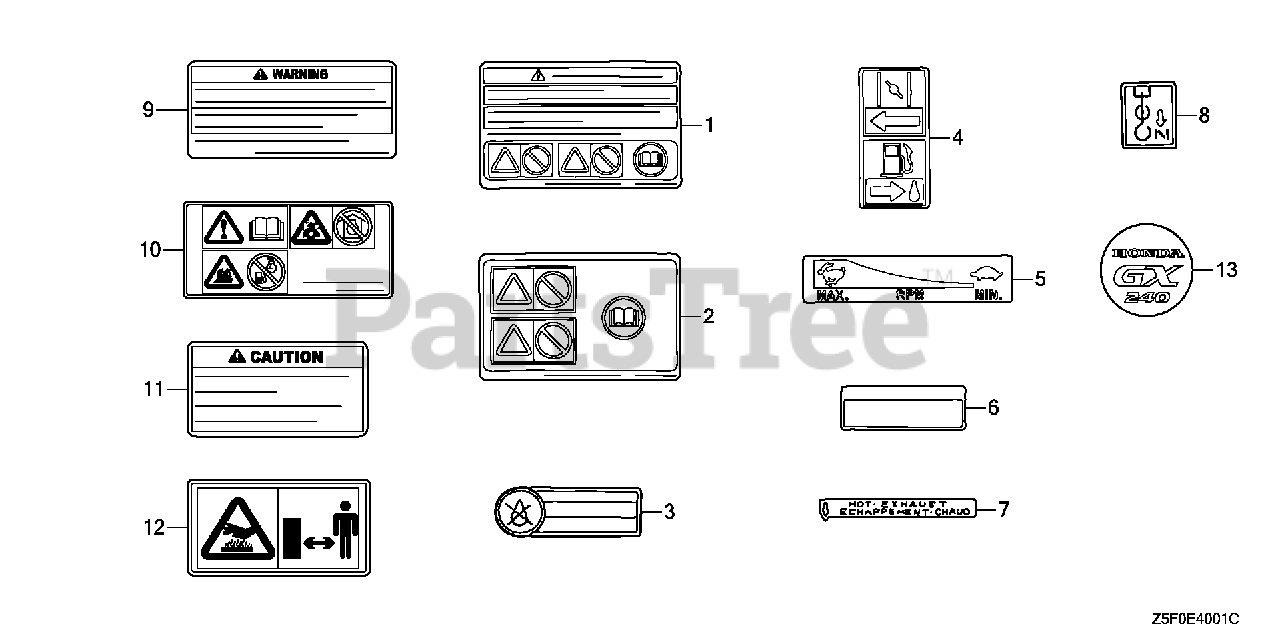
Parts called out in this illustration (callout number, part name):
1	MARK, OPERATOR CAUTION (ENGLISH)(MADE IN JAPAN)
1	MARK, OPERATOR CAUTION (FRENCH)(MADE IN JAPAN)
2	MARK, OPERATOR CAUTION (PICTOGRAPH)(MADE IN JAPAN)
